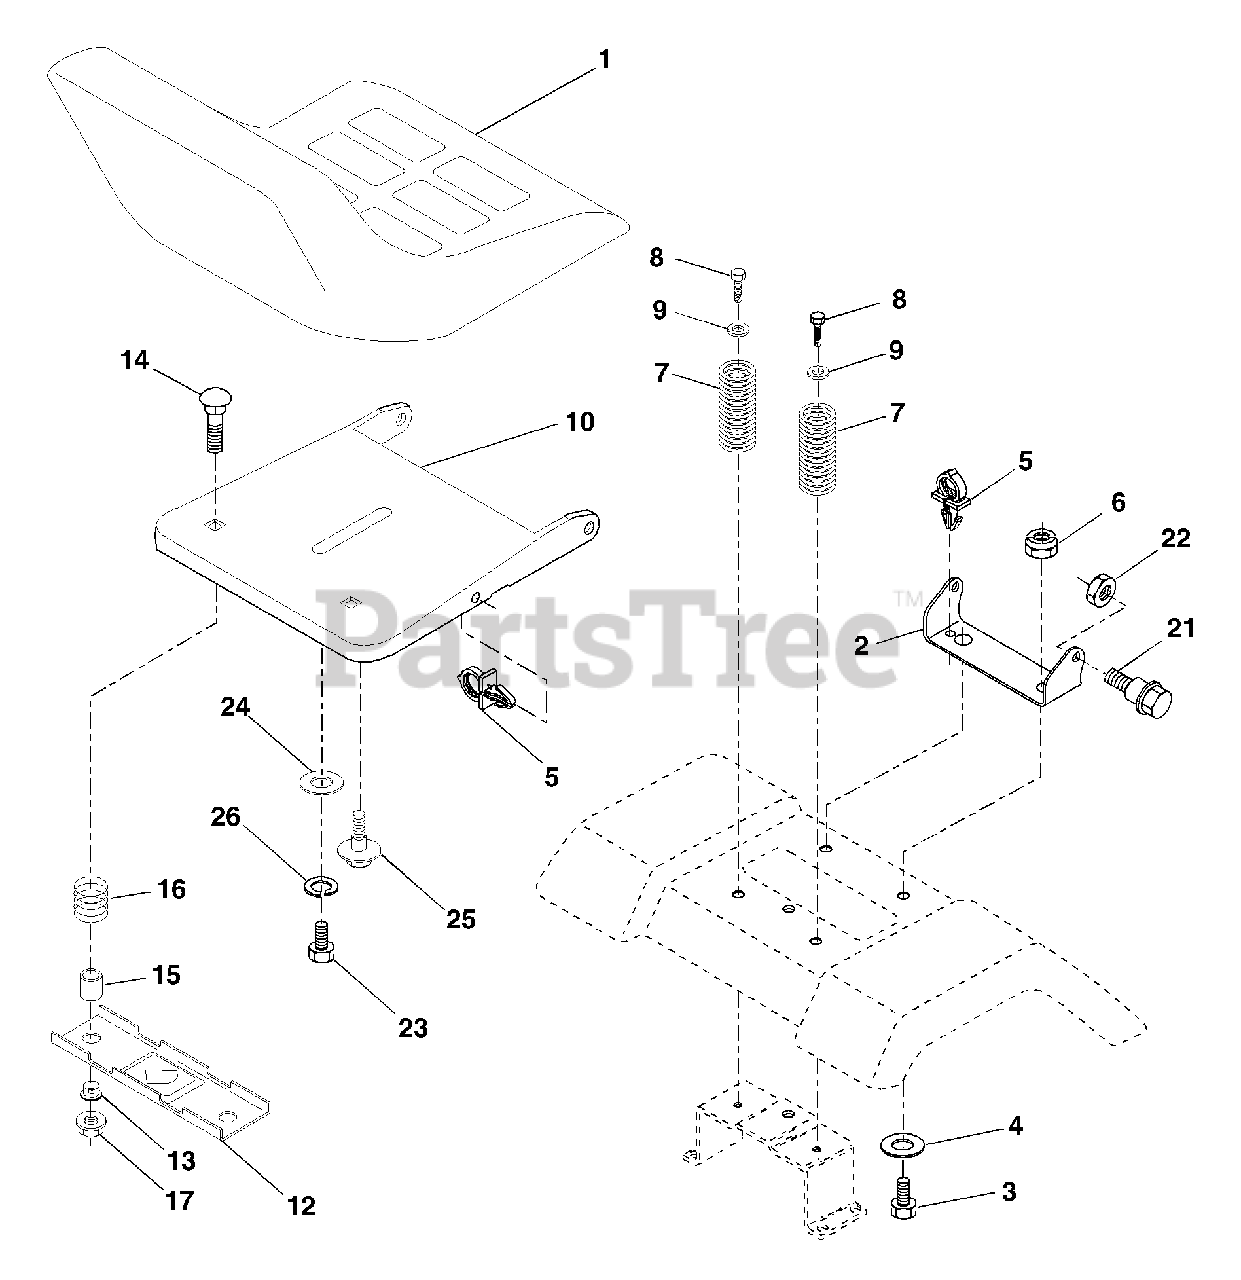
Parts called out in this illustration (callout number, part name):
2	Bracket Pnt Pivot Seat (blk)
3	Bolt
4	Washer 13/32 X 1 X 10 Ga
5	Clip Push-In Hinged
6	Nut
7	Spring Seat Cprsn 2 250 Blk Zi
8	Screw 3/8-16 X 1-1/2
9	Washer 13/32 X 1 X 14 Ga
10	Pan Pnt Seat (blk)
12	Bracket Pnt Mounting Switch
13	Bushing Snap Blk Nyl 50 Id
14	Bolt Rdhd Sht Nk 1/4-20x1-1/2
15	Spacer Split 28 X96 Yel Zinc
16	Spring Cprsn 1 27 Blk Pnt
17	Nut Lock 1/4 Lge Flg Gr 5 Zinc
21	Bolt Shoulder 5/16-18 Unc Blkz-2A
22	Nut
23	Bolt Fin Hex 1/2-13 X 7/8 Gr 5
24	Washer 17/32 X 1-3/16 X 12 Ga
25	Bolt Shoulder 5/16-18 X 62
26	Lockwasher
